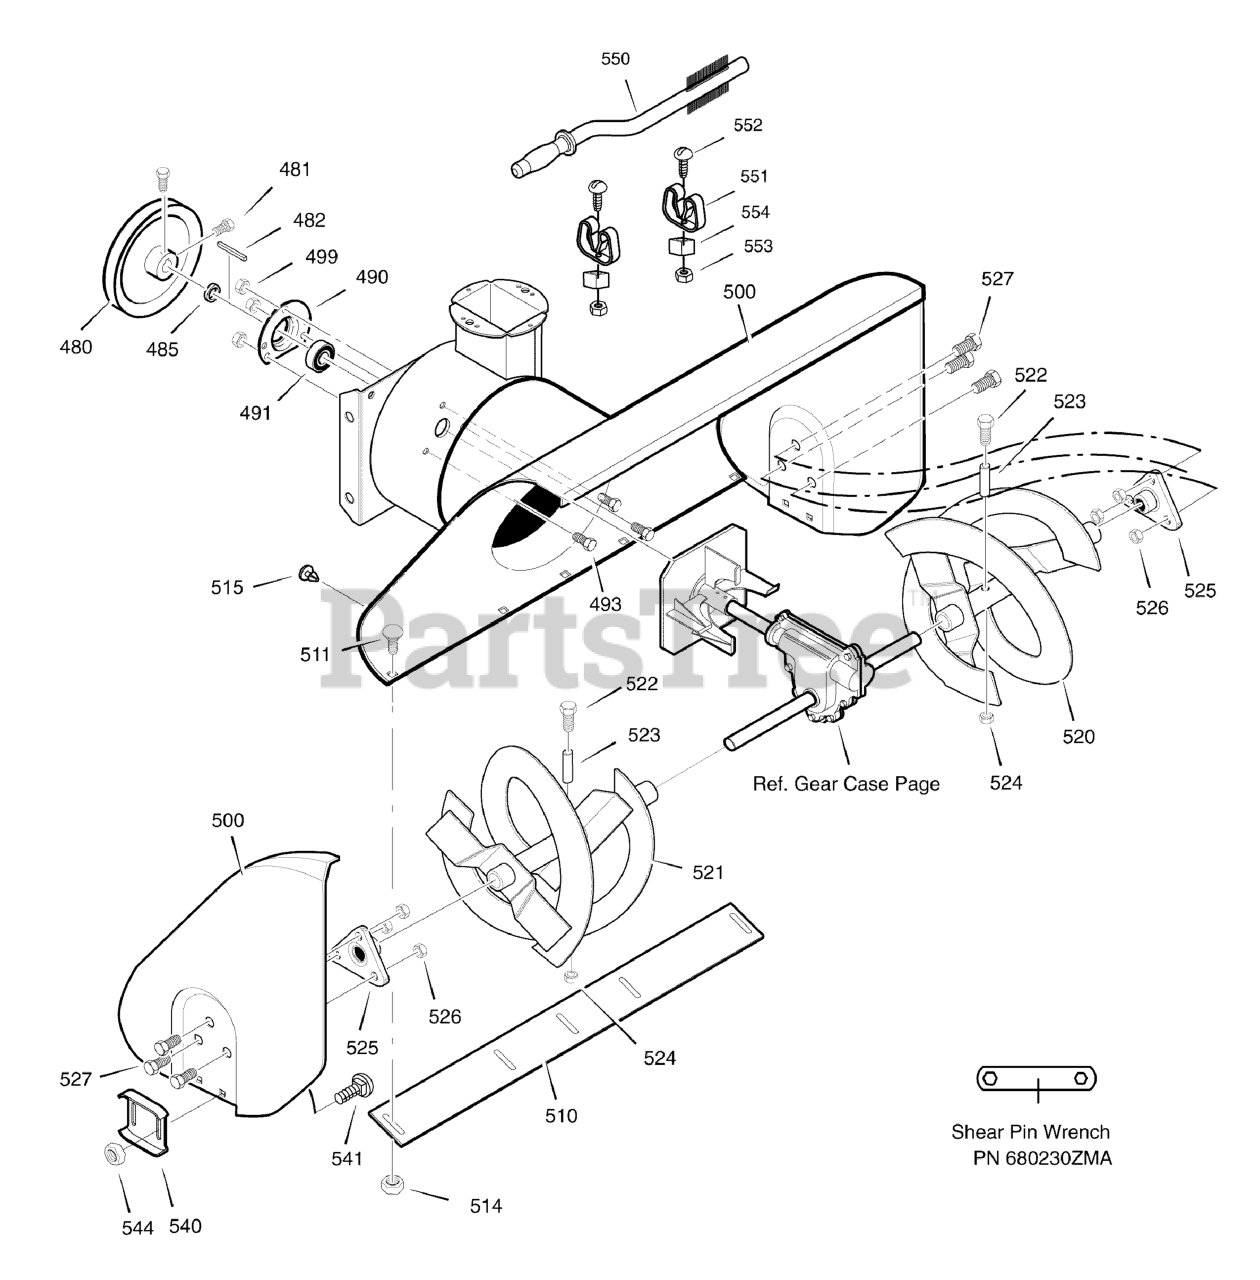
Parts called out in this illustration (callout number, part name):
480	PULLEY, 4L 6.12 X .67
481	SCREW, 5/16-18 x 0.63
482	KEY, SQUARE 3/16 X 3/4
485	SPACER, FRICTION PULLEY
490	RETAINER, BALL BEARING
491	BEARING, BALL
493	BOLT, HEX 5/16-18 X .62
499	NUT, 5/16-18 HEXWDFLLK
500	HOUSING, ASSEMBLY
510	BLADE, SCRAPER 24"
511	BOLT, 1/4-20 X 0.75
514	NUT, 1/4-20
515	FASTENER, RATCHET
520	AUGER, ASSEMBLY, LH
521	AUGER, ASSEMBLY, RH
522	SCREW, 1/4-20 X 1.75
523	SPACER, SLEEVE
524	NUT, 1/4-20
525	BEARING, FLANGE
526	NUT, 5/16-18
527	SCREW, 5/16-18 x 0.75
540	SKID, HEIGHT ADJUST
541	BOLT, 5/16-18 X .50
544	NUT, 5/16-18
550	BRUSH, CLEANOUT
551	CLIP, RETAINER
552	SCREW
553	NUT
